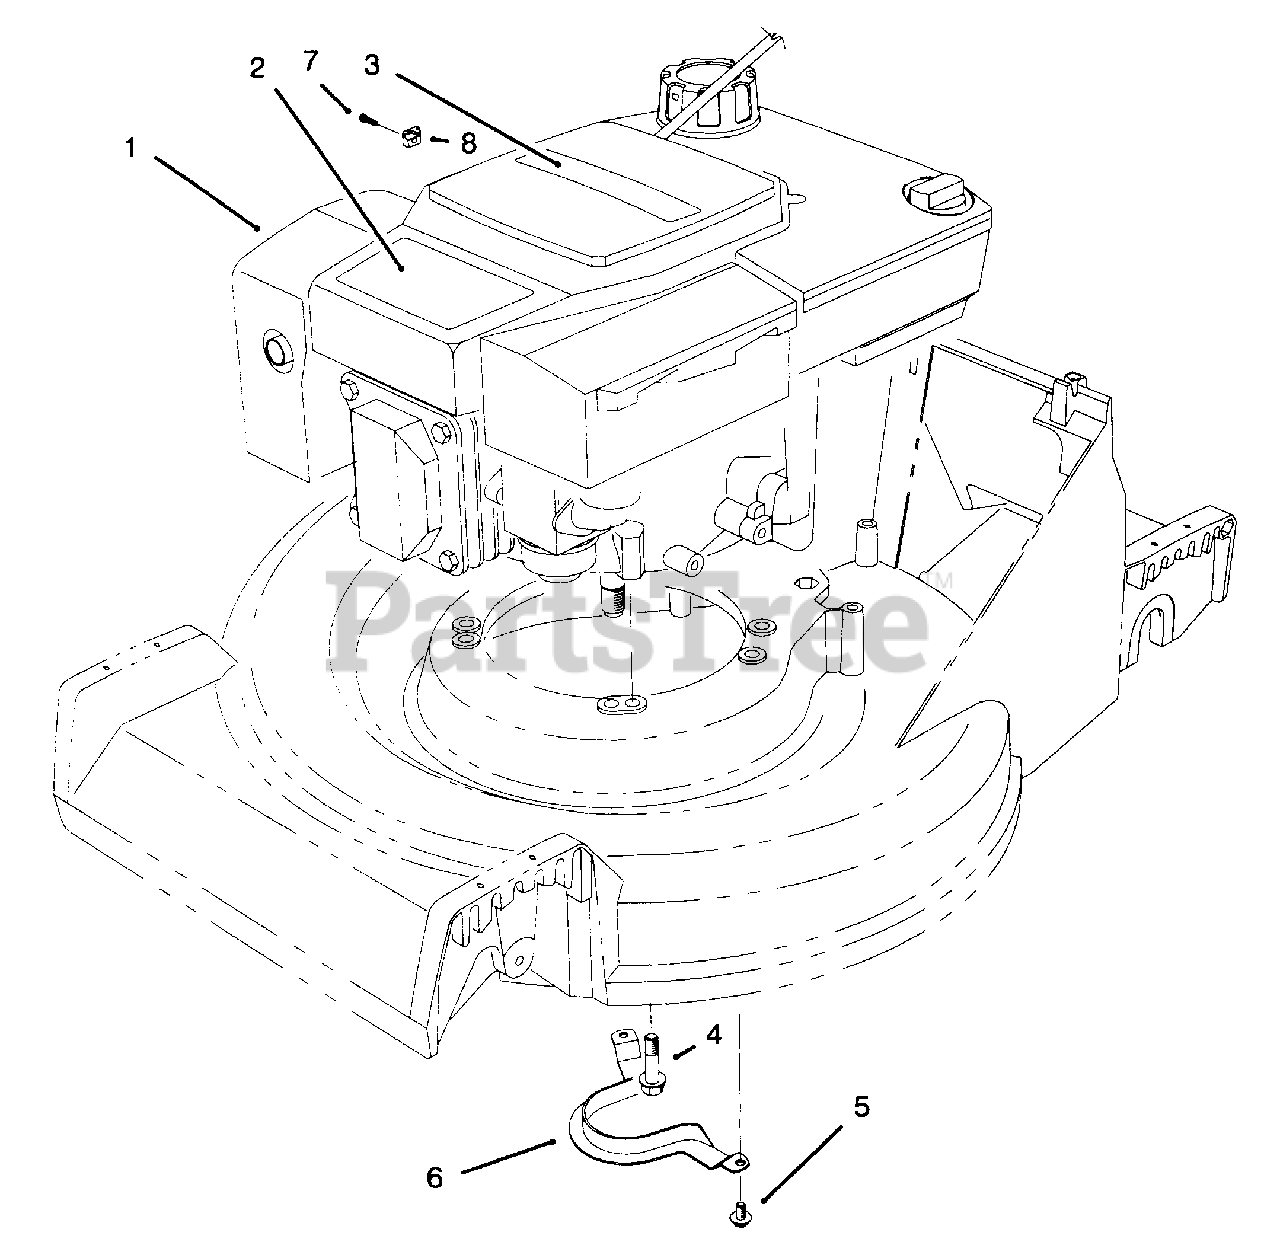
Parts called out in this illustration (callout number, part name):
1	Engine
2	Decal-Recoil
3	Applique-Shroud
4	Screw-Tapping
5	Screw-Tapping
6	Guide-Belt
7	Screw P/W Engine
8	Clamp P/W Engine
